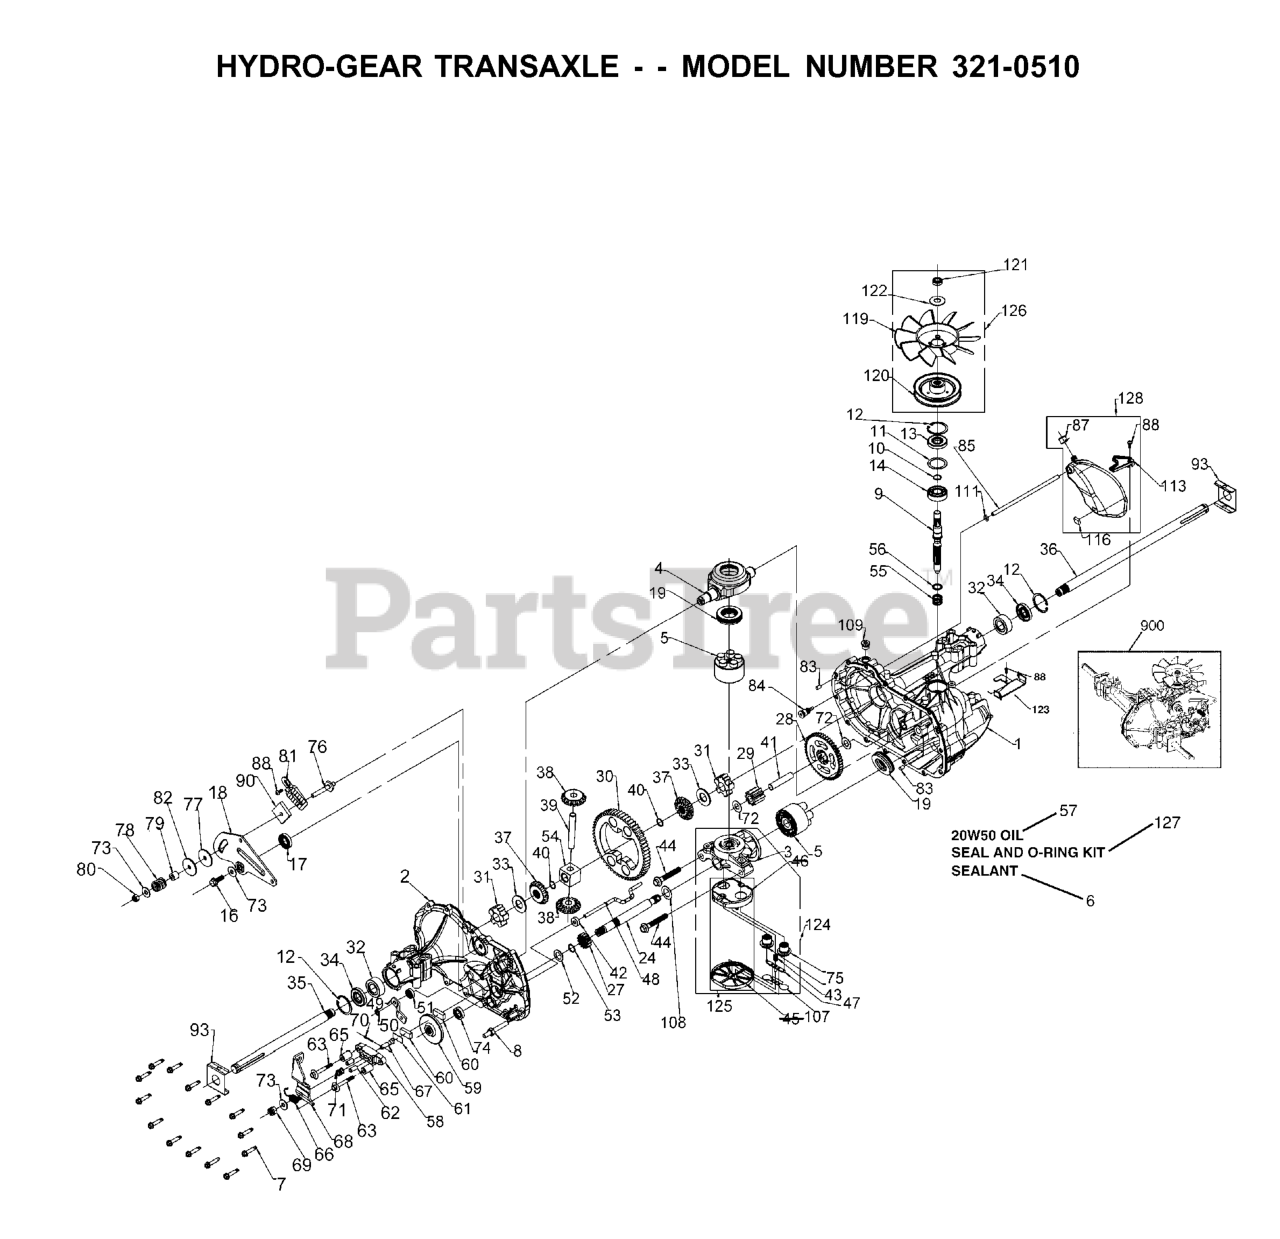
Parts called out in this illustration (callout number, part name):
5	KIT CYLINDER #70331
14	BALL BEARING 17X40X12 50315
33	WASHER.HYDRO-GEAR 44875
39	SHAFT.50146
55	SPRING 2003014
60	BRAKE PUCK (44132)
61	PUCK PLATE 44134
62	BRAKE PIN 44127
64	BOLT W/NYLOCK 44433
73	WASHER .34X.88X.06.44130
78	SPRING HELICAL COMP 50277
79	SPACER.HYDRO GEAR 50278
80	LOCKNUT, HEX 5/16-24
